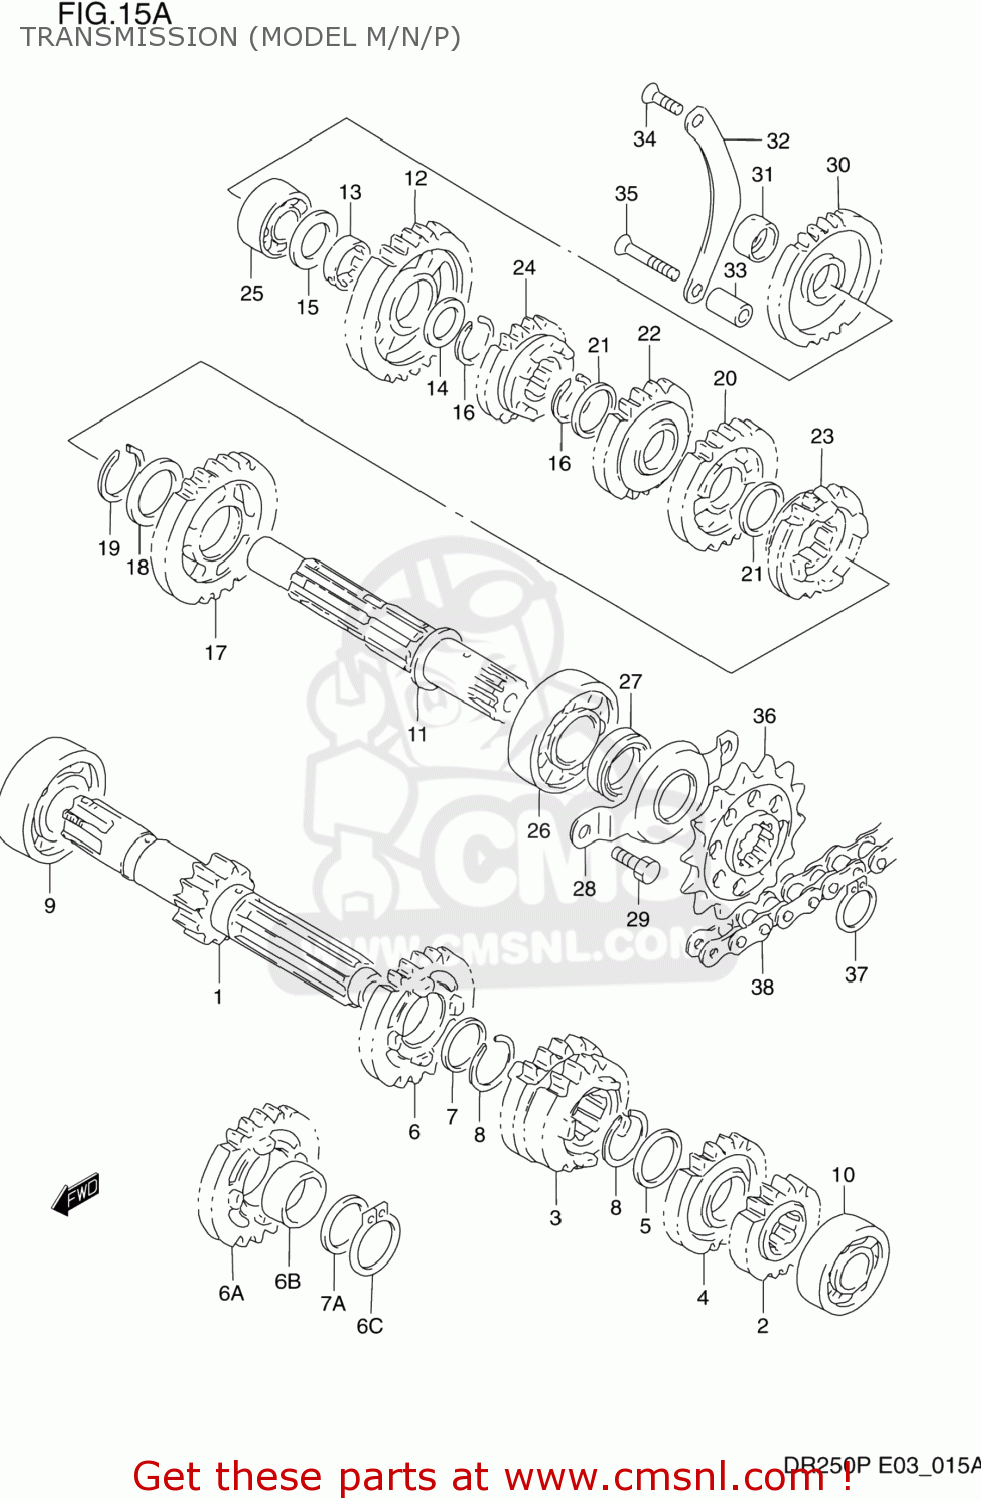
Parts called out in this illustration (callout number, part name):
1	SHAFT,COUNTER
2	GEAR,SECOND DRIVE (NT:15)
3	GEAR,3RD & 4TH DRIVE(NT:18/18)
4	GEAR,5TH DRIVE(NT:21)
5	WASHER
6	GEAR COMP,SIXTH DRIVE
6A	GEAR,6TH DRIVE(NT:23)
6B	BUSH(22X26X9)
6C	CIRCLIP
7	SHIM
7A	WASHER,THRUST
8	CIRCLIP
9	BEARING
10	BEARING
11	SHAFT,DRIVE
12	GEAR,FIRST DRIVEN (NT:29)
13	BUSH,1ST DRIVEN GEAR
14	WASHER
15	WASHER,THRUST
16	CIRCLIP
17	GEAR,2ND DRIVEN(NT:26)
18	WASHER
19	CIRCLIP
20	GEAR,THIRD DRIVEN
21	SHIM
22	GEAR,4TH DRIVEN(NT:20)
23	GEAR,FIFTH DRIVEN (NT:20)
24	GEAR,SIXTH DRIVEN
25	BEARING(17X40X17.5)
26	BEARING(22X56X16)
27	SEAL,OIL(22X34X7)
28	RETAINER,DRIVE SHAFT OIL SEAL
29	BOLT
30	GEAR,KICK STARTER IDLE(NT:27)
31	BUSH,KICK STARTER IDLE GEAR
32	RETAINER,KICK IDLE GEAR
33	SPACER (6.5X12X21)
34	SCREW
35	SCREW
36	SPROCKET,ENGINE
37	CIRCLIP
38	CHAIN ASSEMBLY,DRIVE RK520
